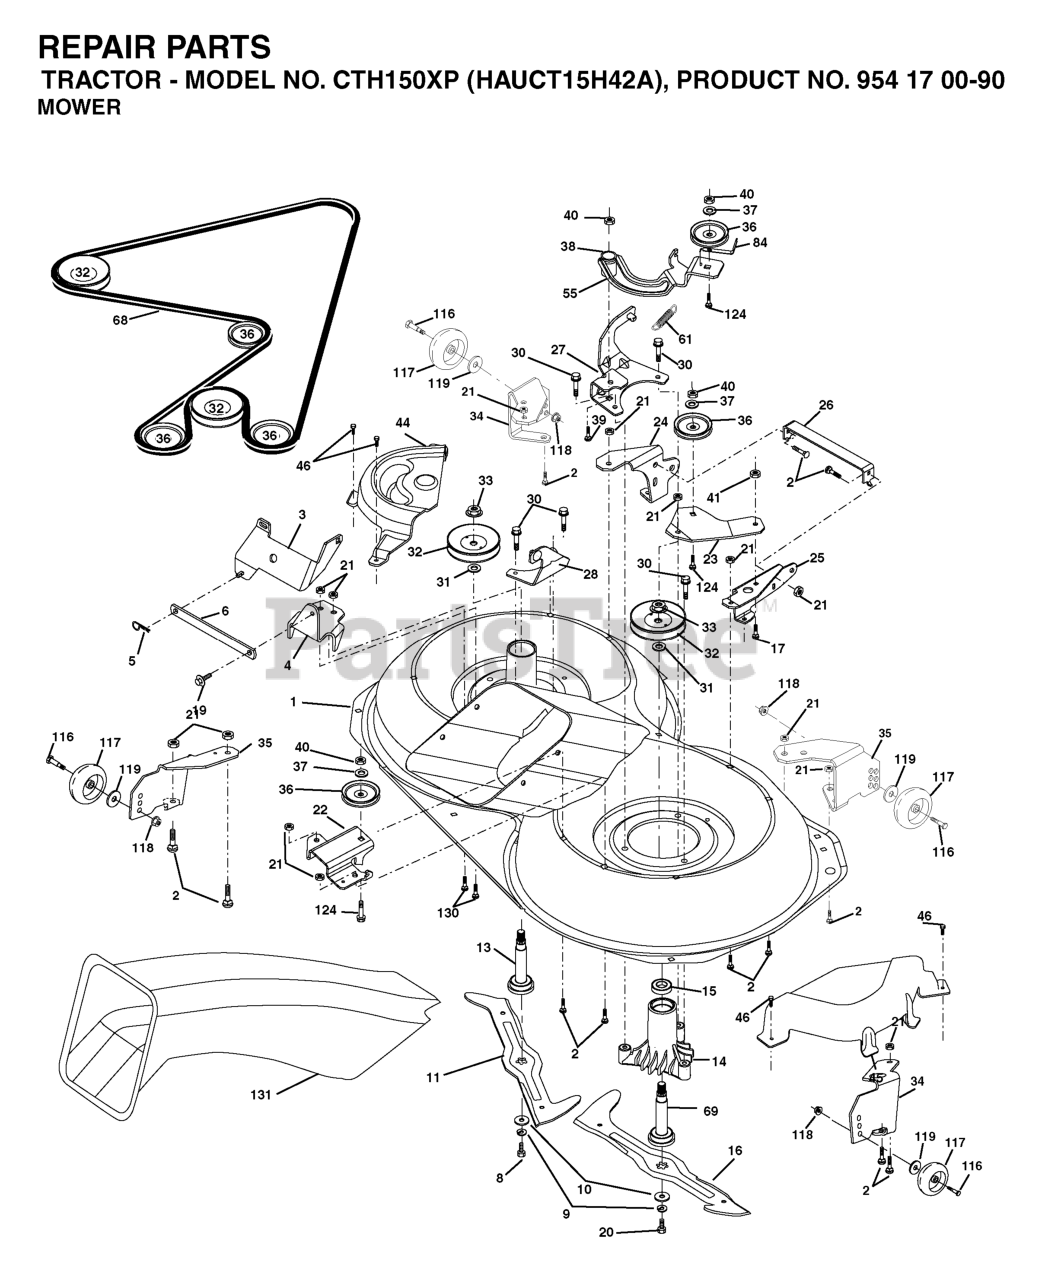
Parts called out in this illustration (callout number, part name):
1	Housing Asm. Mower 107 CRD
2	RP BOLT 5/16-18 X3/4 ZN/YEL GR
5	RETAINER SPRING
6	BAR.SWAY.92.CRD
8	BLADE BOLT
9	LOCKWASHER
10	WASHER.BLADE
11	BLADE, LH (CTH150)
13	SHAFT ASM VENT
14	HOUSING.MANDREL.VENTED (MACHD)
16	RP BLADE RH (CTH150)
17	BOLT D
19	BOLT SHD 5/16-18
21	LOCKNUT
22	BRACKET.IDLER.RR.107.CRD
25	BRACKET.SUSPENSION.RF.107.CRD
26	BRACE.SUPT.SUSP.FRT.CRD
28	BRACKET
30	SCREW, WASHER HEAD
31	WASHER
33	NUT, FLG TOPLOCK 9/16"
36	PULLEY.IDLER.4.25
37	WASHER
45	COVER.MANDREL.RH.CRD
46	SCREW.1/4-20X5/8
55	ARM.IDLER.107.CRD
68	HEX-BELT 107 MOWER
69	SHAFT.ASM.W/LWR.BRG.RH.THREAD
84	KEEPER, BELT IDLER
116	BOLT, SHOULDER
117	WHEEL GAGE DONUT
118	LOCKNUT
119	WASHER.5/16.FLAT.STE.STD.
124	BOLT.3/8-16X1.50
130	BOLT.CARR.SQNK.5/16-18UNC.X3/4
131	CHUTE BAGGER
